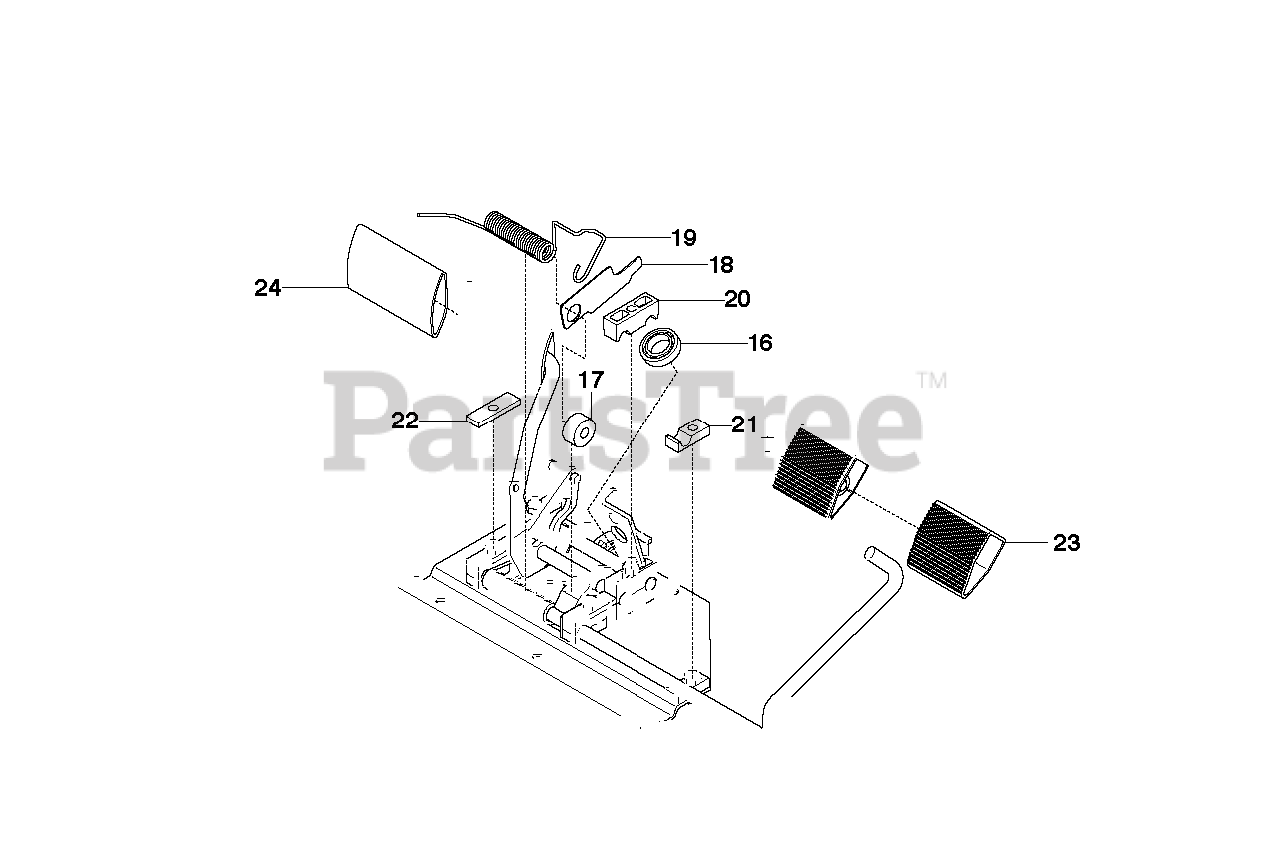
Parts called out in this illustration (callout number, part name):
16	BALL BEARING 6002-2RS1
17	ROLLER
18	PLATE
19	SPRING
20	PEDAL SHAFT CLAMP
21	SUPPORT
22	PLATE
23	PEDAL RUBBER
24	PEDAL RUBBER, SF
